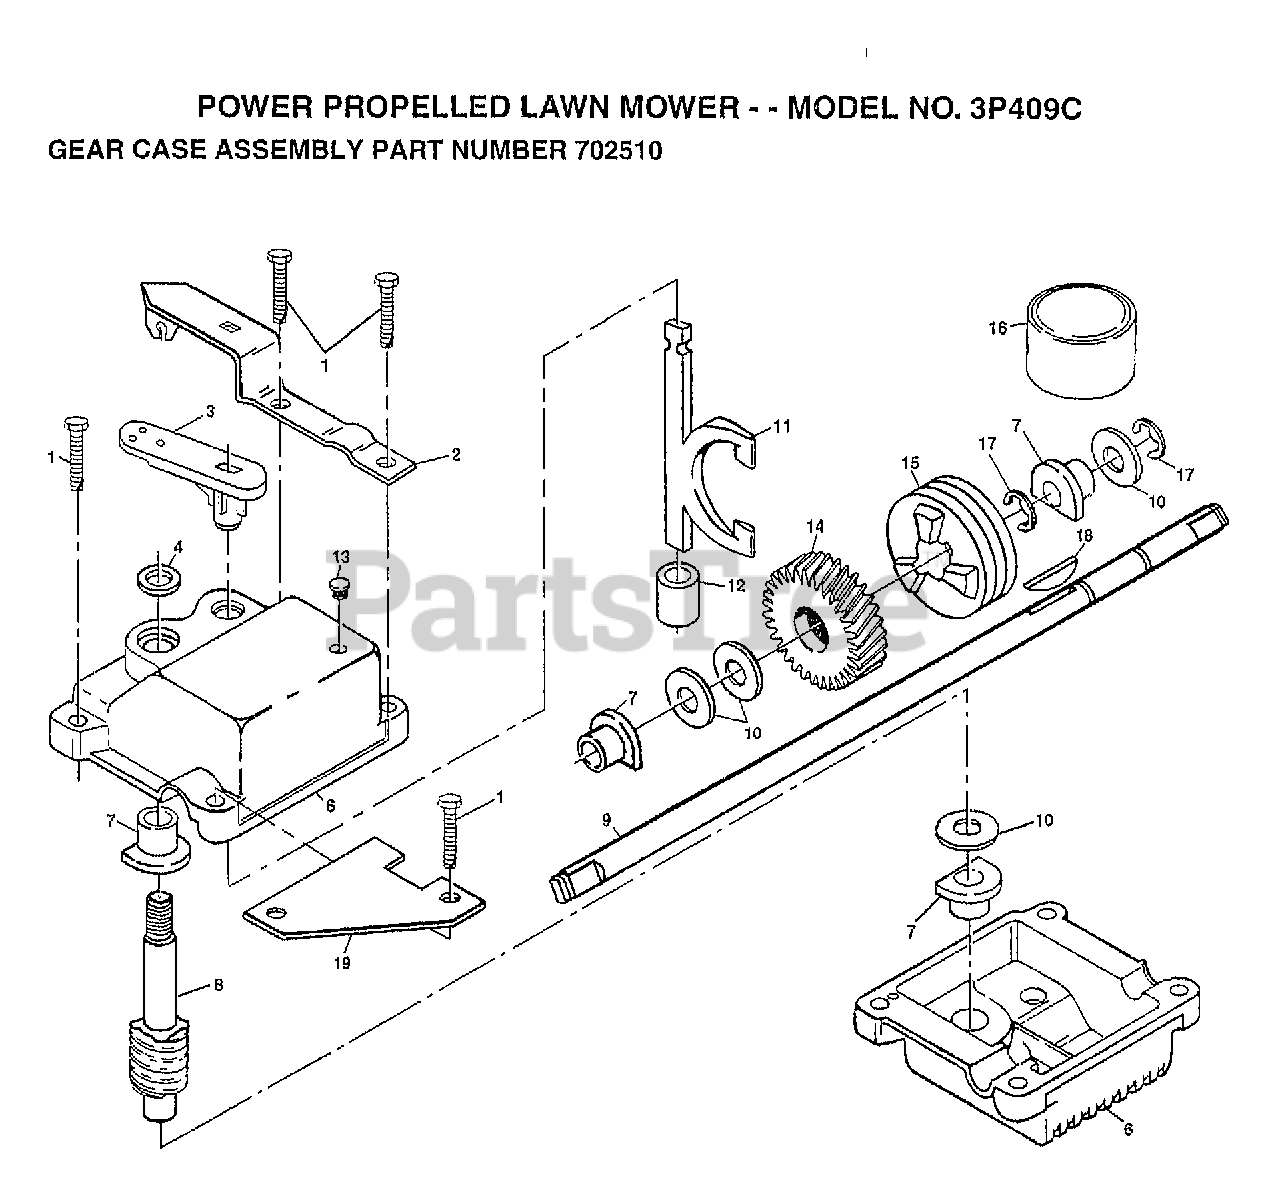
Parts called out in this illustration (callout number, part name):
1	SCREW.1/4-20
2	BRACKET.GEARCASE
3	SHIFTER
4	SEAL
6	KIT GEARCASE HALV
7	BEARING
8	SHAFT.WORM
9	SHAFT.DRIVE.SD
10	THRUST WASHER
11	CLUTCH YOKE
12	BUSHING.GEAR BOX
13	PLUG PM
14	GEAR.HELICAL
15	CLUTCH JAW
17	RING T
18	HI PRO KEY
